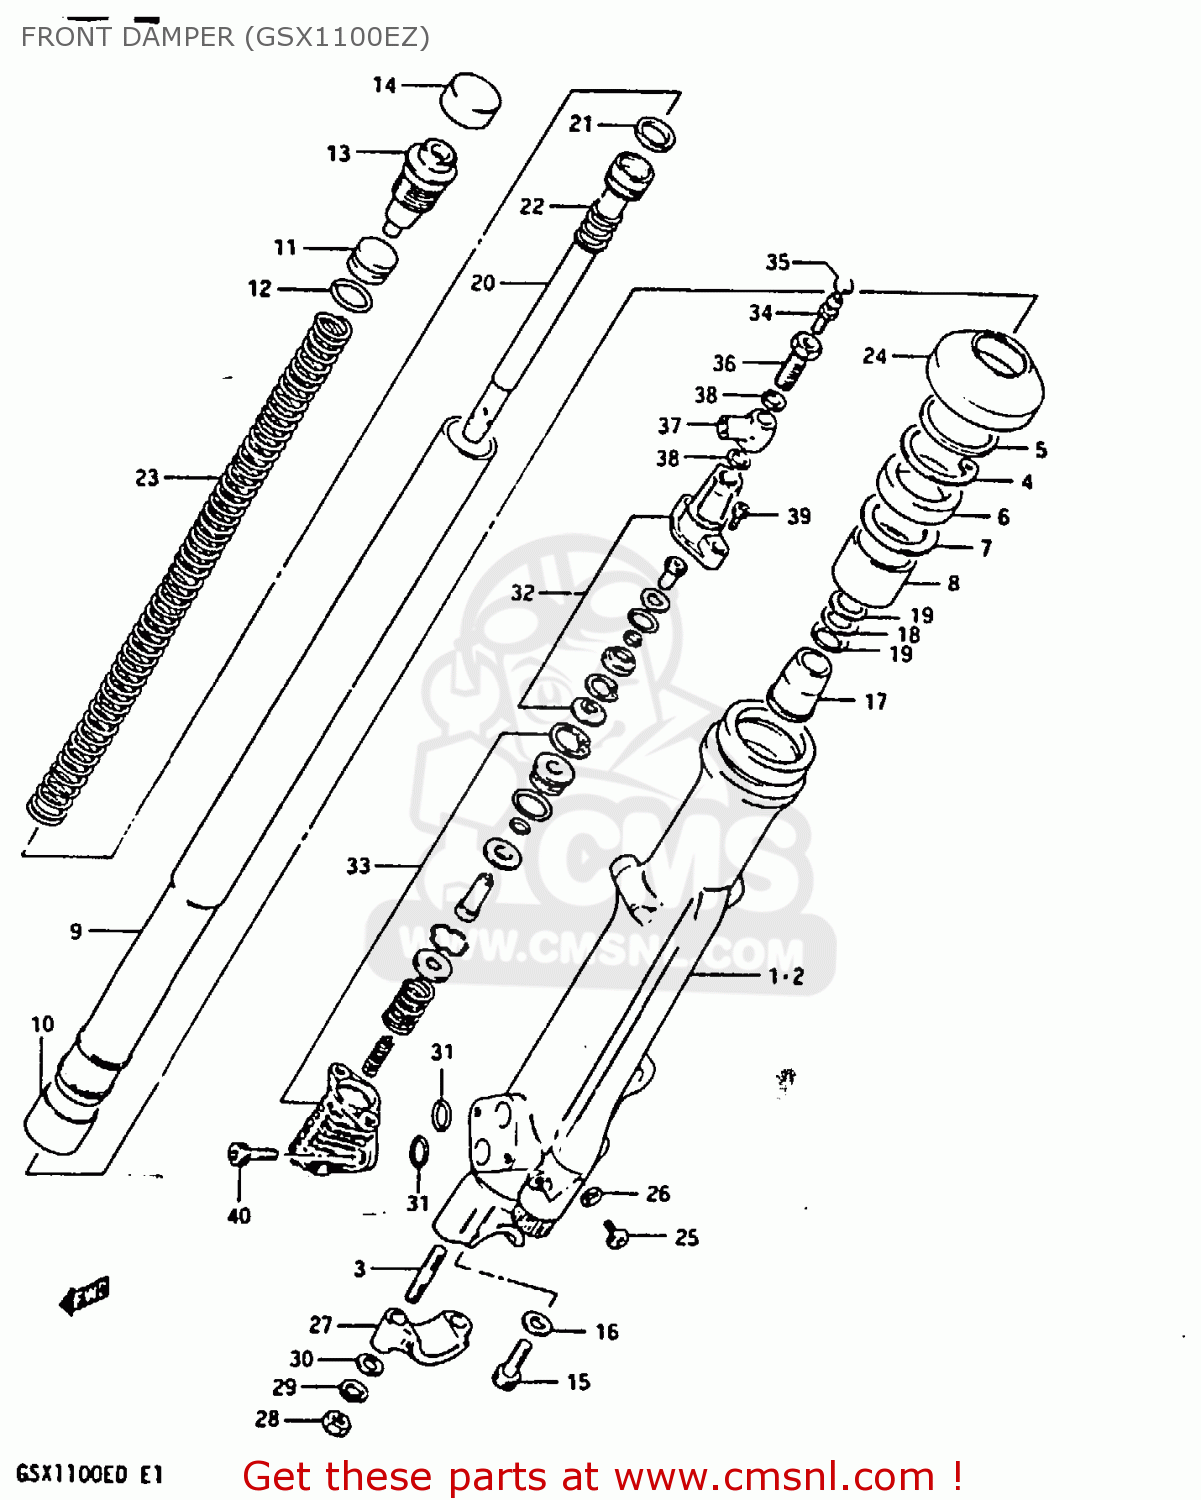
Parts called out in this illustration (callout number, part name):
1	OUTER TUBE, RH
2	OUTER TUBE, LH
3	STUD 8X30
4	RING,STOPPER
5	WASHER. FRONT FORK
6	OIL SEAL,FRONT FORK
7	WASHER
8	METAL,SLIDE
9	INNER TUBE
10	METAL,FRONT FORK PISTON
11	PISTON,FREE
12	O-RING
13	CAP
14	CAP,RUBBER
15	BOLT,FORK CYLINDER(10X25)
16	GASKET (NAS)
17	PIECE,OIL LOCK
18	WASHER
19	SPRING,LEAF
20	CYLINDER
21	RING,PISTON
22	SPRING,FORK REBOUND
23	SPRING
24	SEAL,DUST
25	SCREW
26	GASKET,DRAIN,PLUG (NAS)
27	HOLDER,AXLE
28	NUT (8MM)
29	LOCK WASHER
30	WASHER
31	O RING
32	MODULATOR PARTS SET,FRONT
33	MODULATOR VALVE SET,FRONT
34	BREATHER,AIR
35	CAP,BREADER
36	BOLT,UNION
37	SPACER,FRONT FORK MODULATOR
38	WASHER
39	BOLT,FR FORK
40	BOLT,FRONT FORK
